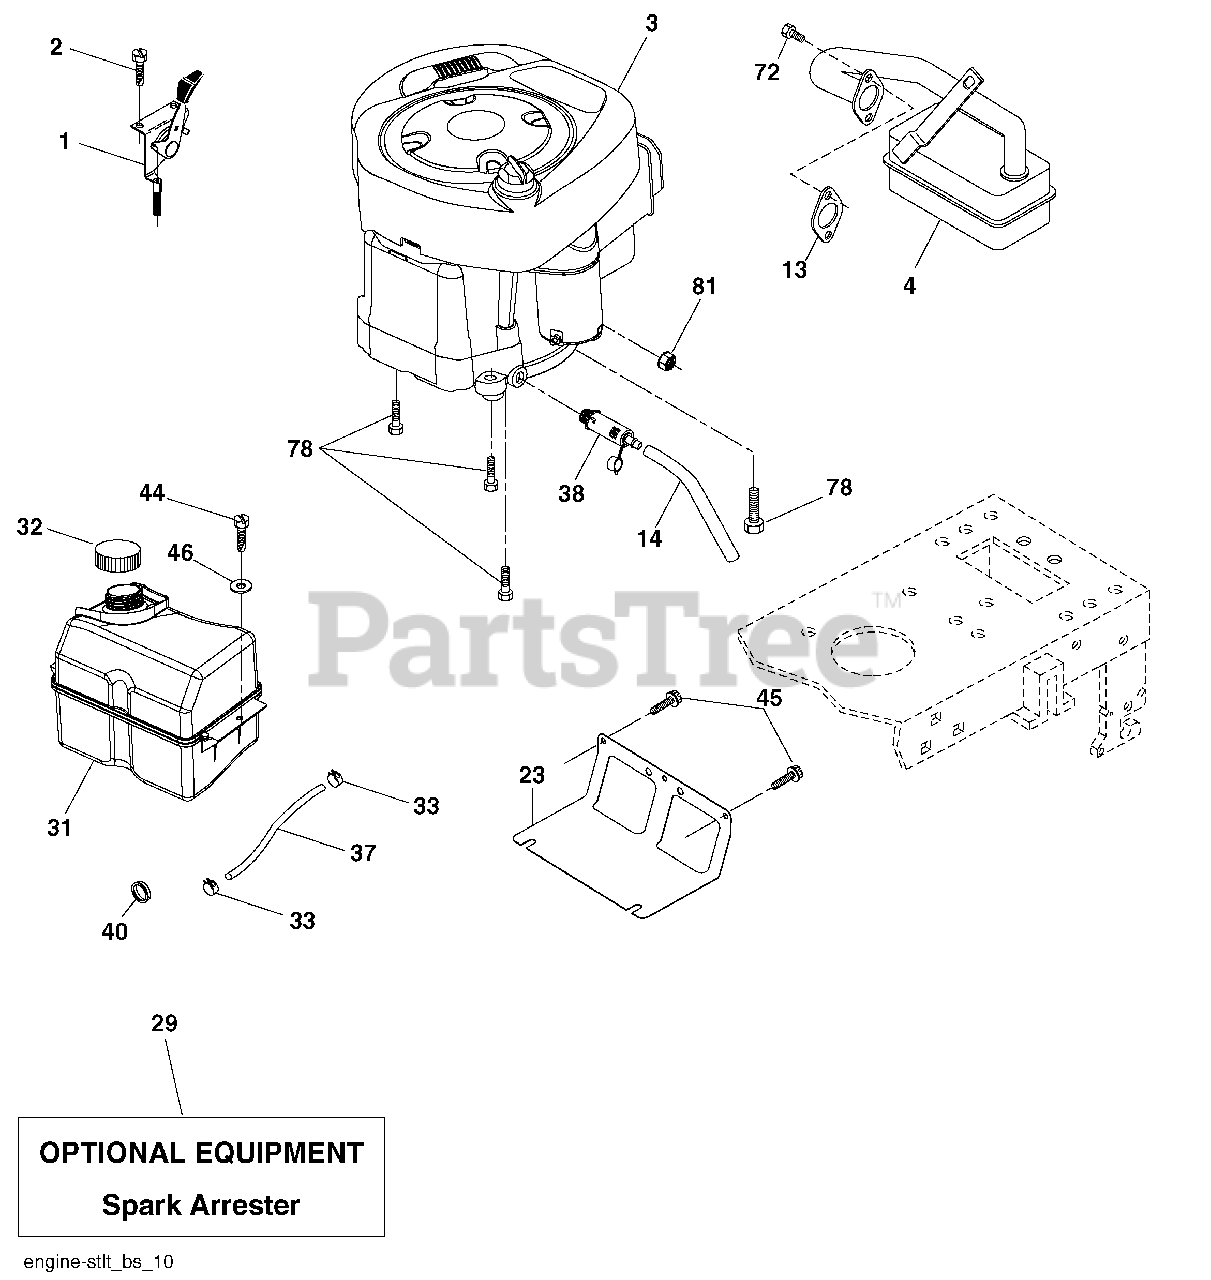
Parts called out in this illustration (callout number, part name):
1	Control Th/ch Flag
2	Screw Hex Thd Cut 1/4-20 x 1/2
4	Muffler Exhaust B&S
13	Gasket Eng 1 313 Id Tin Plated
14	Tube Drain Oil Easy
23	Shield BRN/DBR Guard
29	Kit Spark Arrestor (Flat Scrn)
31	Tank Fuel Front
32	Cap Asm Fuel
33	Clamp Hose
37	Line Fuel 20"
38	Plug Drain Oil
40	Bushing Snap
44	Screw Thdrol 1/4-20 x 3/4
45	Screw Hex Wsh Thdrol 3/8-16
46	Washer 9/32 x 7/8 x 16 Ga.
72	Screw Socket Hd 5/16-18 x .75
78	Screw 3/8-16 x 1-1/4
81	Nut Keps Hex 1/4-20 unc
